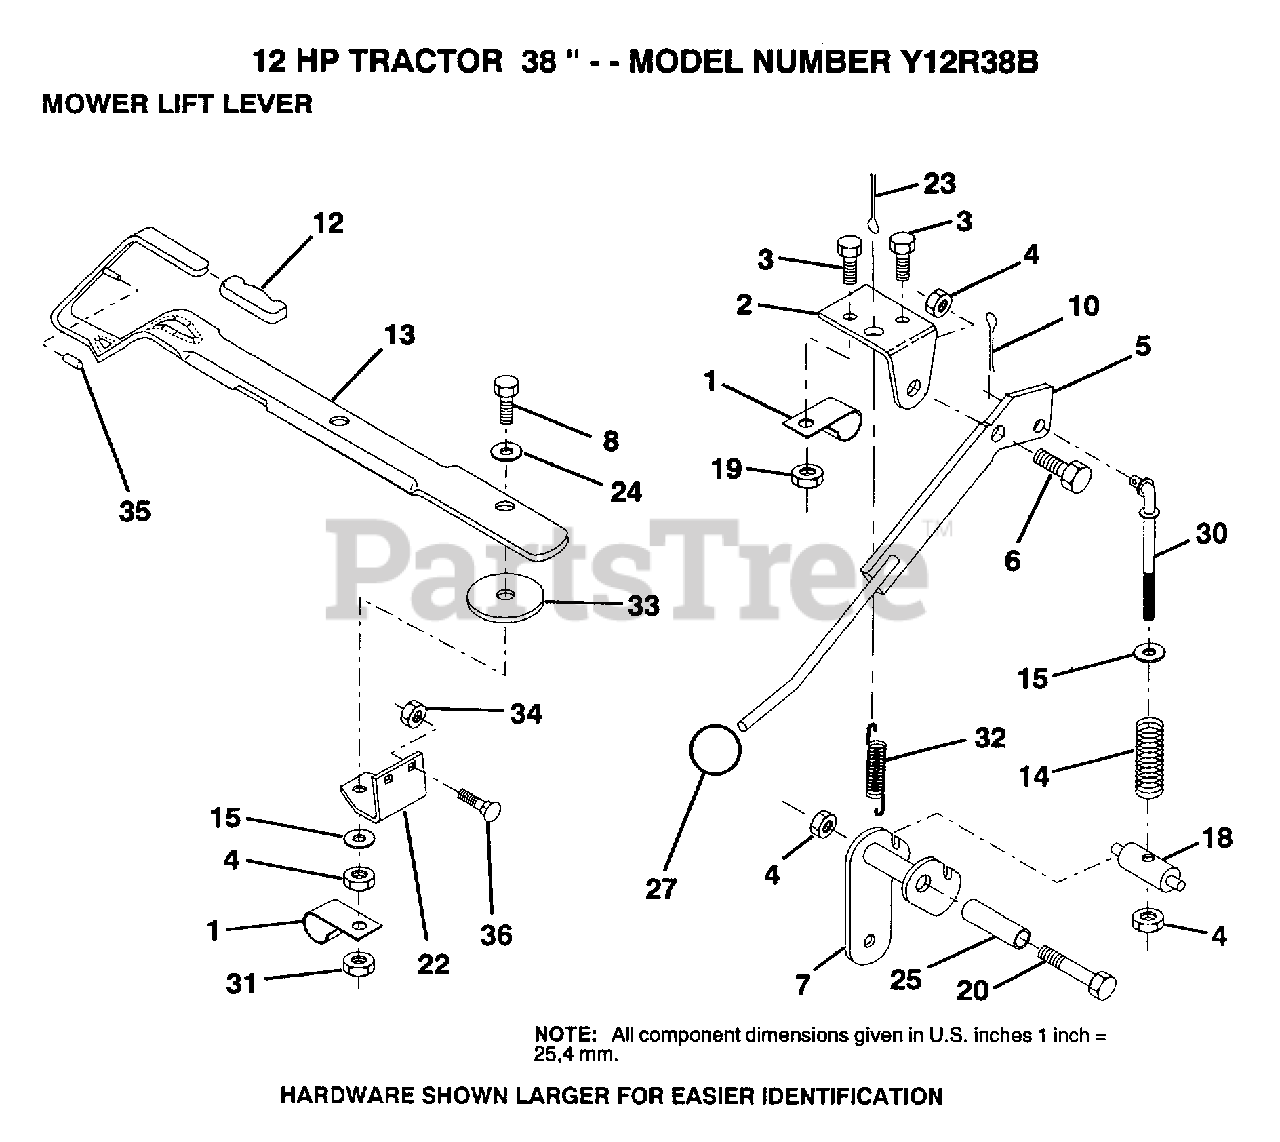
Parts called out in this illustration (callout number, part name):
1	"CLIP,INSULATOR"
2	BRKT CLUTCH
3	BOLT
5	CLUTCH LEVER AS
6	"BOLT, SHOULDER LT"
7	MWR CLUT ARM ASM
8	BOLT
10	COTTER PIN
12	GRIP HANDLE
13	LEVER LIFT LR
14	COMP CLUTCH SPRNG
15	WASHER HYT
18	TRUNNION
20	BOLT
22	LIFT LEVER BRKT
24	WASHER
25	TUBE SPACER
27	KNOB
30	ROD TENSION CLUTC
31	LOCKNUT
32	SPRING EXT
33	WASHER
35	VINYL CAP RED
36	BOLT
